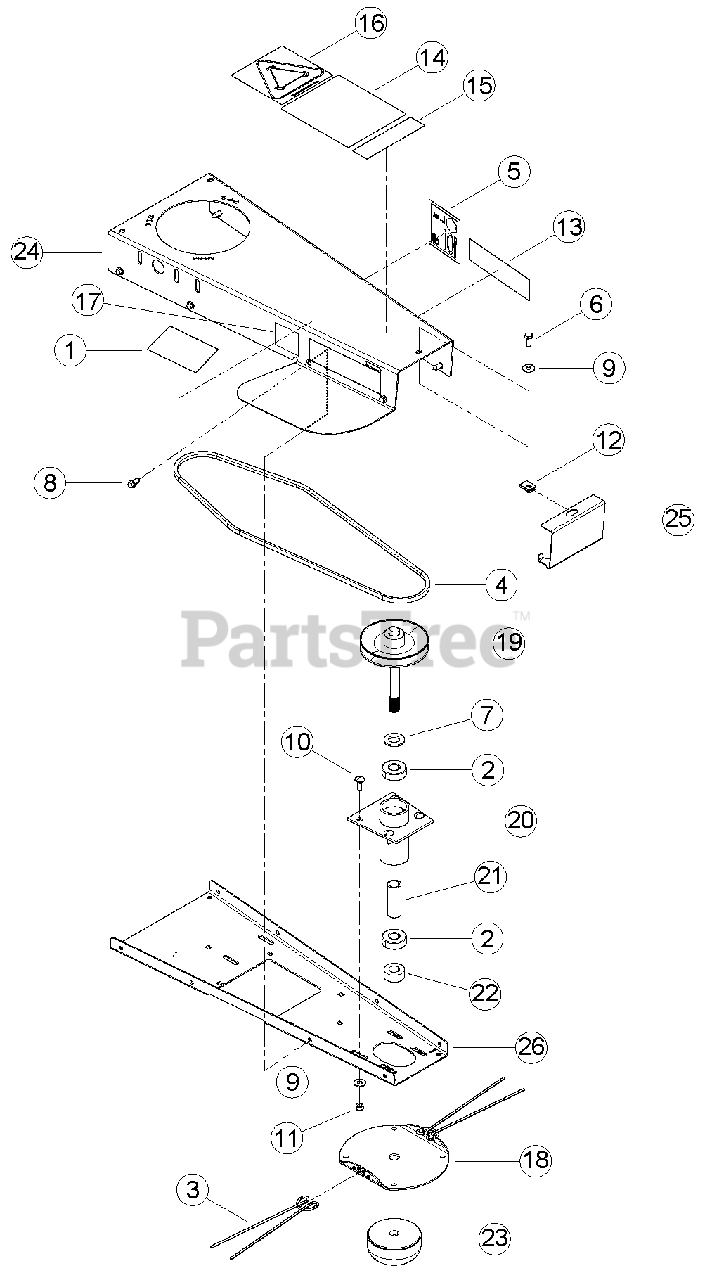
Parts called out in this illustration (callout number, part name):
1	DECAL, GRINDER DANGER
2	BEARING, 3/4 BALL
3	STRING, .155 X 20-1/2
4	BELT, 3L X 52
5	DECAL, 98 DB (WT160S)
5	DECAL, 101 DB (WT190S)
6	BOLT, 5/16 3/4 HEX HD GR5 ZP
7	WASHER, 3/4 SAE FLAT ZP
8	SCREW, 11/32 X 7/8 HWH AB THREAD ZP
9	WASHER, 5/16 FLAT ZP
10	BOLT, 5/16 X 7/8 CRG GR5 NC ZP
11	NUT, 5/16 NE NYLOCK ZP
12	NUT 5/16-18 TINNERMAN U-TYPE
13	DECAL, ECHO BEARCAT 6.82 X 1.90
14	DECAL, MANUAL/SAFETY INFO
15	DECAL, MODEL WT160S
15	DECAL, MODEL WT190S
16	DECAL, RECLAIM IT
17	DECAL, ECHO BEAR CAT QR CODE
18	DISK, TRIMMER HEAD
19	WELDMENT, TRIMMER PULLEY
20	WELDMENT, SPINDLE HUB
21	SPACER, TRIMMER SPINDLE
22	SPACER, TRIMMER HEAD
24	BODY, TRIMMER
25	COVER, FRONT TRIMMER
26	BOTTOM, TRIMMER FRAME
